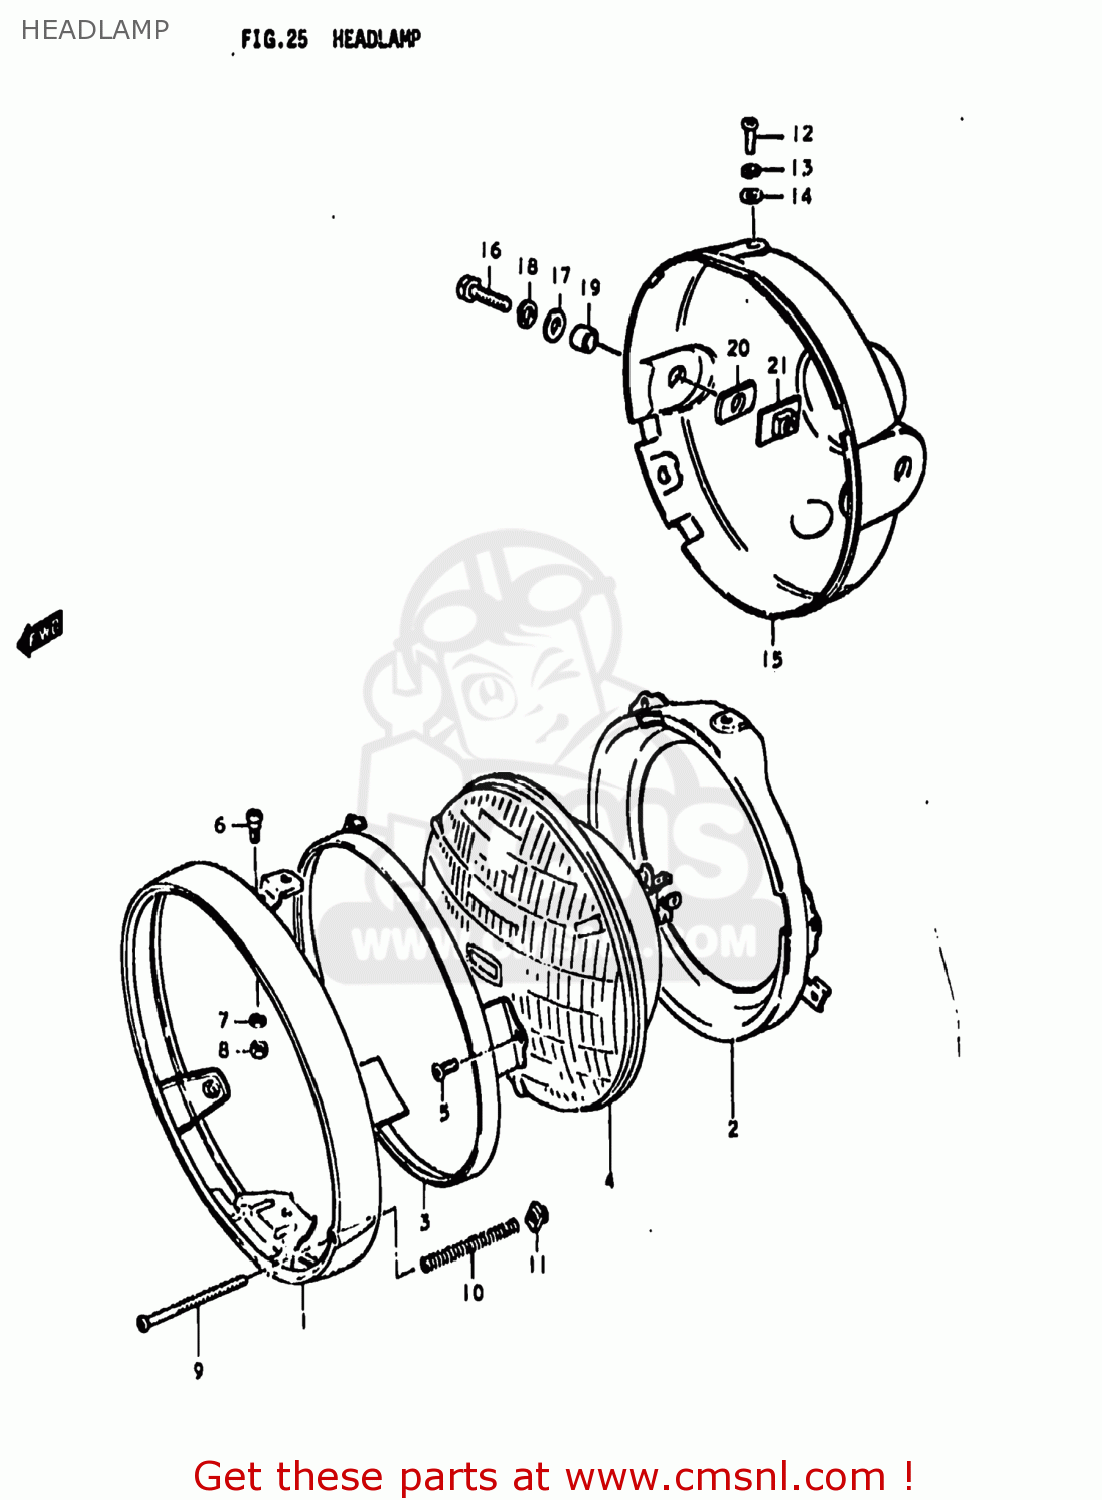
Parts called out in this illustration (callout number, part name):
1	RIM
2	RING
3	RETAINING RING
4	UNIT,HEADLAMP
5	SCREW
6	H/LAMP LENS UNIT FITING SCRE
7	LOCK WASHER
8	NUT
9	SCREW,HEADLAMP ADJUST
10	SPRING,ADJUSTING
11	NUT
12	SCREW
13	WASHER,LOCK
14	WASHER
15	HOUSING,HEADLAMP(BLACK)
16	BOLT
17	WASHER
18	LOCK WASHER
19	SPACER (8.8X12X7)
20	CUSHION
21	PLATE,HEADLAMP HOUSING
